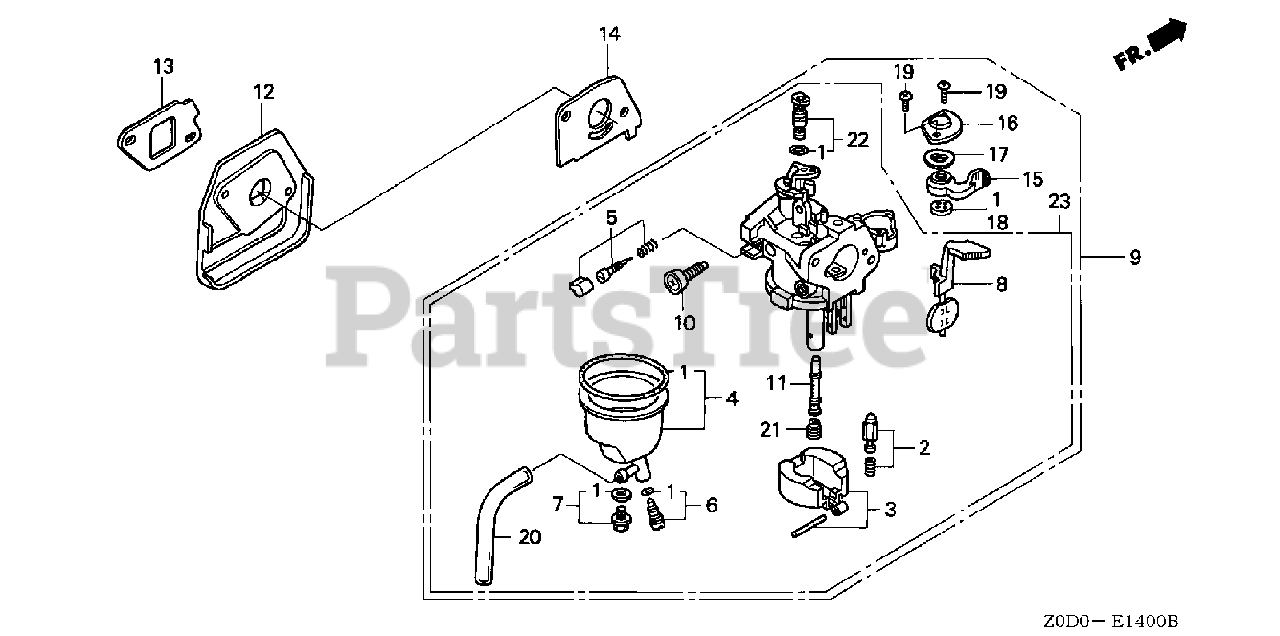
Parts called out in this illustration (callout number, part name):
1	GASKET SET
2	VALVE SET, FLOAT
3	FLOAT SET
4	CHAMBER SET, FLOAT
5	SCREW SET
6	SCREW SET, DRAIN
7	SCREW SET
8	CHOKE SET
9	CARBURETOR ASSY. (BF32F A)
10	SCREW, THROTTLE STOP
11	NOZZLE, MAIN
12	INSULATOR, CARBURETOR
13	GASKET, INSULATOR
14	GASKET, CARBURETOR
15	LEVER, COCK
16	PLATE, LEVER SETTING
17	SPRING, VALVE LEVER
18	GASKET, VALVE
19	SCREW, PAN (3X6)
20	BULK HOSE, VINYL (3.5X6.5X8000) (3.5X6.5X100)
21	JET, MAIN (#55)
21	JET, MAIN (#58)
21	JET, MAIN (#60)
22	JET SET, PILOT (#35)
